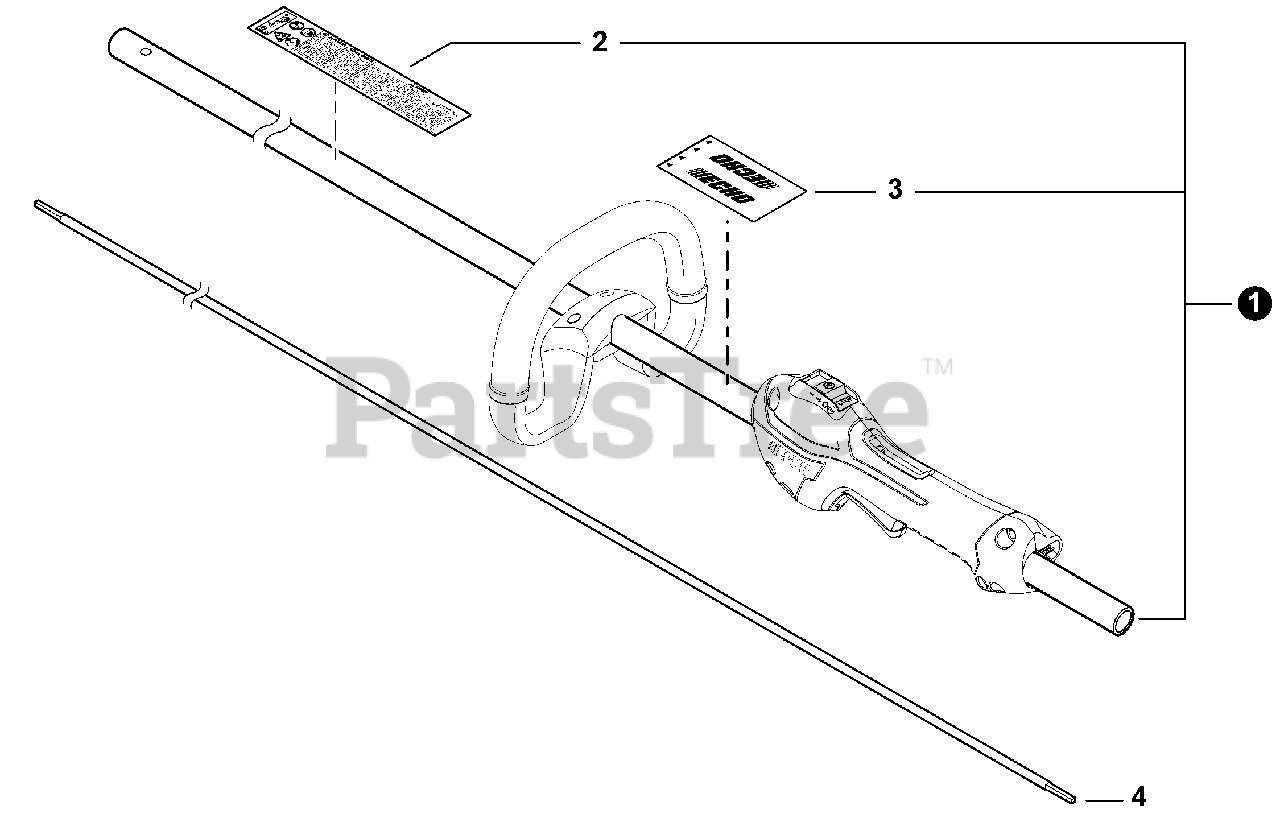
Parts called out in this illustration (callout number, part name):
1	MAIN PIPE ASSY
2	LABEL, CAUTION
3	LABEL, HANDLE LOCATION
4	DRIVESHAFT
